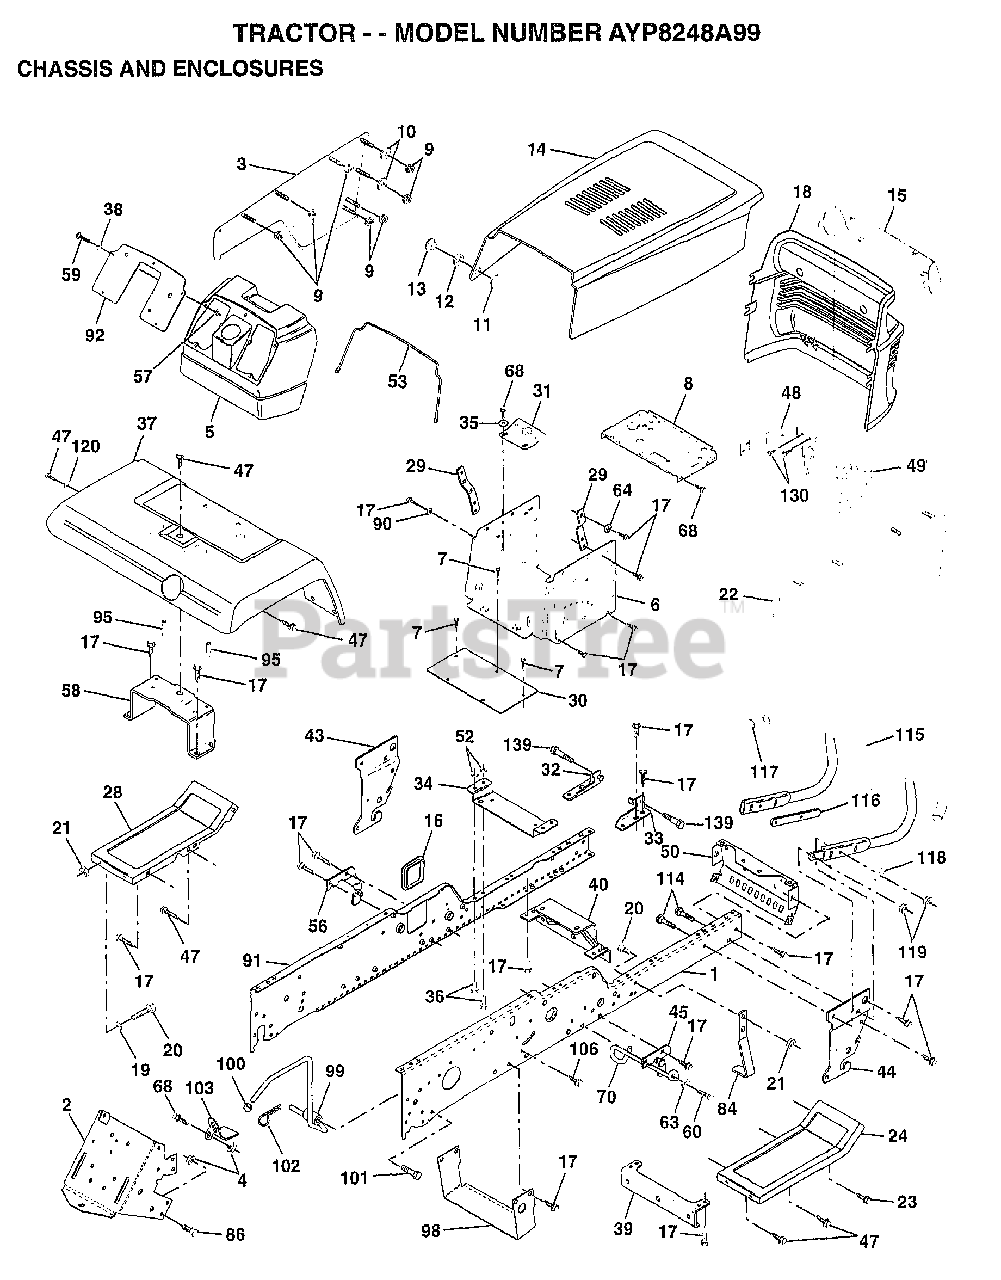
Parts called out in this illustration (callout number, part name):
1	"RAIL,FRAME RH"
2	DRAWBAR GT
3	PANEL.ASM.SIDE.LH
4	NUT.7/16
5	DASH.PLASTIC.BLK
6	DASH LOWER
7	SCREW
8	SUPPORT.DASH.BTRY
9	PAL NUT LT
10	WASHER
11	RIVET.RATCHET.MAL
12	WASHER.NYLON
13	RIVET.RATCH.FEMAL
15	LENS.YT.GT.SEARS
16	COVER ACCESS
17	SCREW
19	WASHER
20	BOLT
22	PANEL.ASM.SIDE.RH
23	SCREW GTV
24	FOOTREST.RH.LT/GT
28	FOOTREST.LT.LT/GT
29	DASH.SUPT.YP/HUSQ
30	SADDLE.HYDRO.95
31	BRKT SUPT 1-PC VG
32	BKRT.PIVOT.CHASSIS.LH
33	BKRT.PIVOT.CHASSIS.RH
34	BRACKET.ENG.SUPT.
35	WASHER
36	BOLT
38	WASHER PM
39	BRACKET.AXLE.FRT.
40	"BRKT SUPPORT,AXLE"
43	BRACKET.SUS.FT.LH
44	BRACKET.SUS.FT.RH
45	BRACKET.SUSP.RH.
47	SCREW LT
48	BRKT ASM PIVOT LH
49	BRKT ASM PIVOT RH
50	"BRKT CHASSIS,FRNT"
53	ROD SUPT HOOD DUC
56	BRACKET.SUSP.LH.
57	NUT HXKEP 1/4X20
58	BRKT.ASM.FENDER
59	SCREW
60	SCREW
63	WASHER
64	WASHER.SERRATED.
68	SCREW LT
70	GUIDE.BELT.MID.SP
72	SCREW
84	STOP.OVER.CENTER
86	BOLT
90	LOCKWASHER
91	"RAIL FRAME,LH"
92	PLATE.SIKLSCREEN.DASH
95	NUT-PUSH YT
98	BRACKET SKID CHAS
99	ROD BYPASS
101	SCREW LT
102	RETAINER M
103	LOCK BYPASS BRKT
114	BOLT.3/8-14X1.25
115	BUMPER.ASM
116	BRACKET.EXT.BUMP.
117	PLUG.PLASTIC
118	WASHER
120	WASHER HYT
130	"SCREW,HWHD.HI-LO#13-16X3/4"
139	BOLT.SHOULDER.5/16-18
